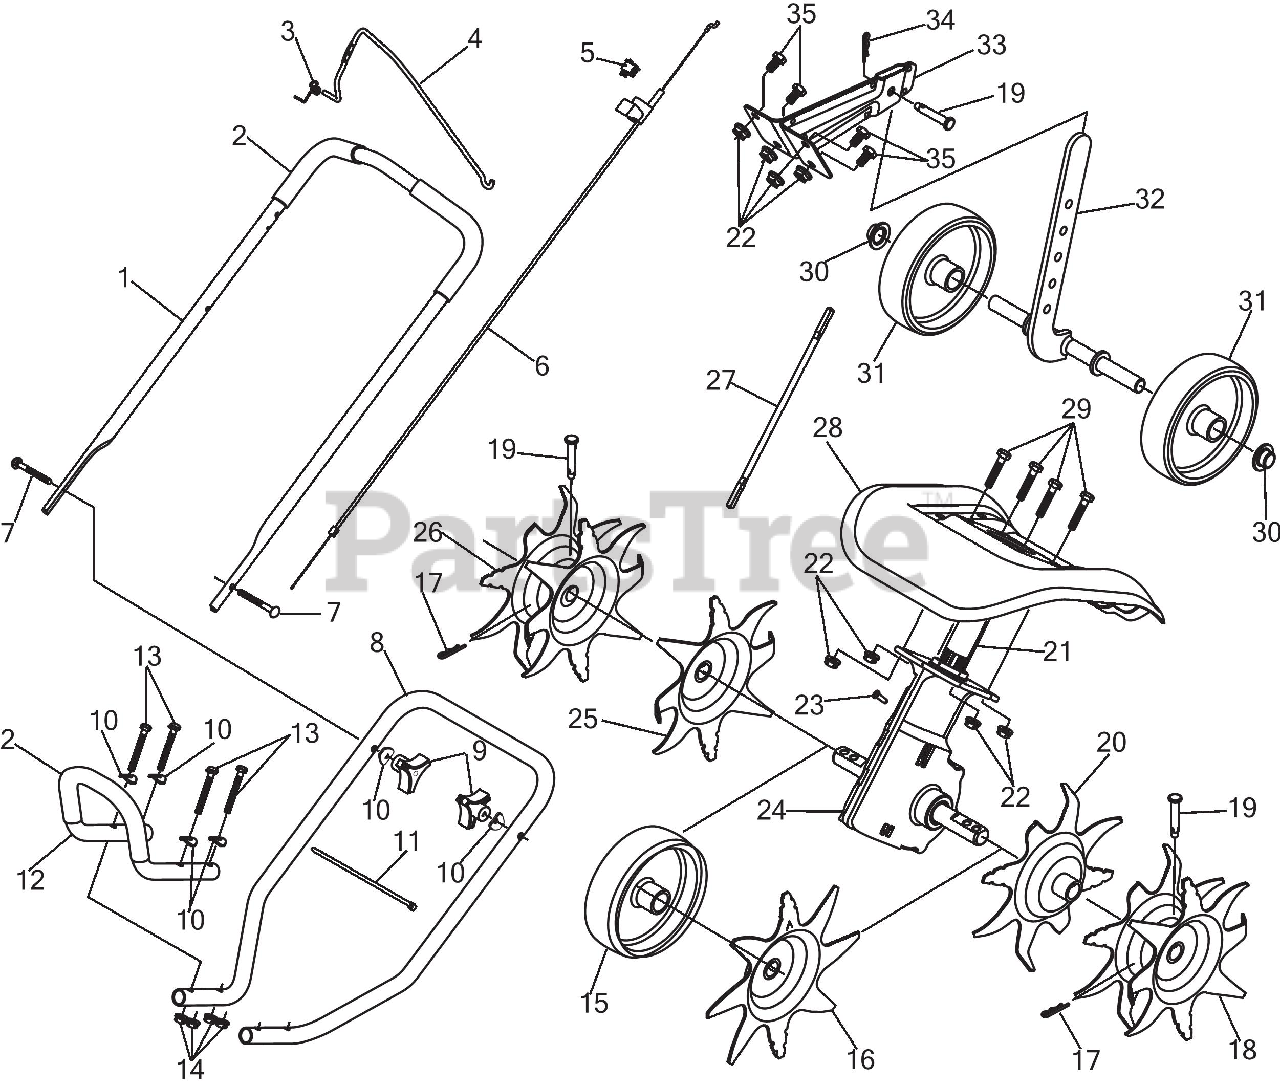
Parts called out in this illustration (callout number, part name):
1	HANDLE UPR
2	FOAM GRIP 9"
3	TORSION SPRING
4	THROTTLE CONTROL BAIL
5	SW, MOMENTARY ON/O
6	THROTTLE CABLE
7	BOLT, CARRIAGE CRV
8	LOWER HANDLE
9	KNOB, 3-PRONG ? "-
10	SADDLE WASHER
11	7" CABLE TIE
12	FRONT HANDLE
14	HEX FLANGE NUT
15	PLASTIC WHEEL 5.0X1.38
16	EDGER TINE
17	COTTER PIN
18	TINE ASSEMBLY (LH)
19	CLEVIS PIN
20	TINE ASSEMBLY (LH)I (RH)O
21	BOOM ASSEMBLY CULT
22	LOCK NUT 1/4
23	SCREW 1/4-20 X.500
24	GEARBOX ASSEMBLY CULT
25	TINE ASSEMBLY (LH)O (RH)I
26	TINE ASSEMBLY (RH)
27	SHAFT-FLEX
28	TINE SHEILD RED
29	HEX SCREW 1/4-20X.
30	PUSH CAP
31	WHEEL 5-1.5 GRAY
32	BRACKET ASSEMBLY
33	TAILPIECE BRACKET ASSEMBLY
34	COTTER PIN .072 DIA
35	HEX SCREW 1/4-20
